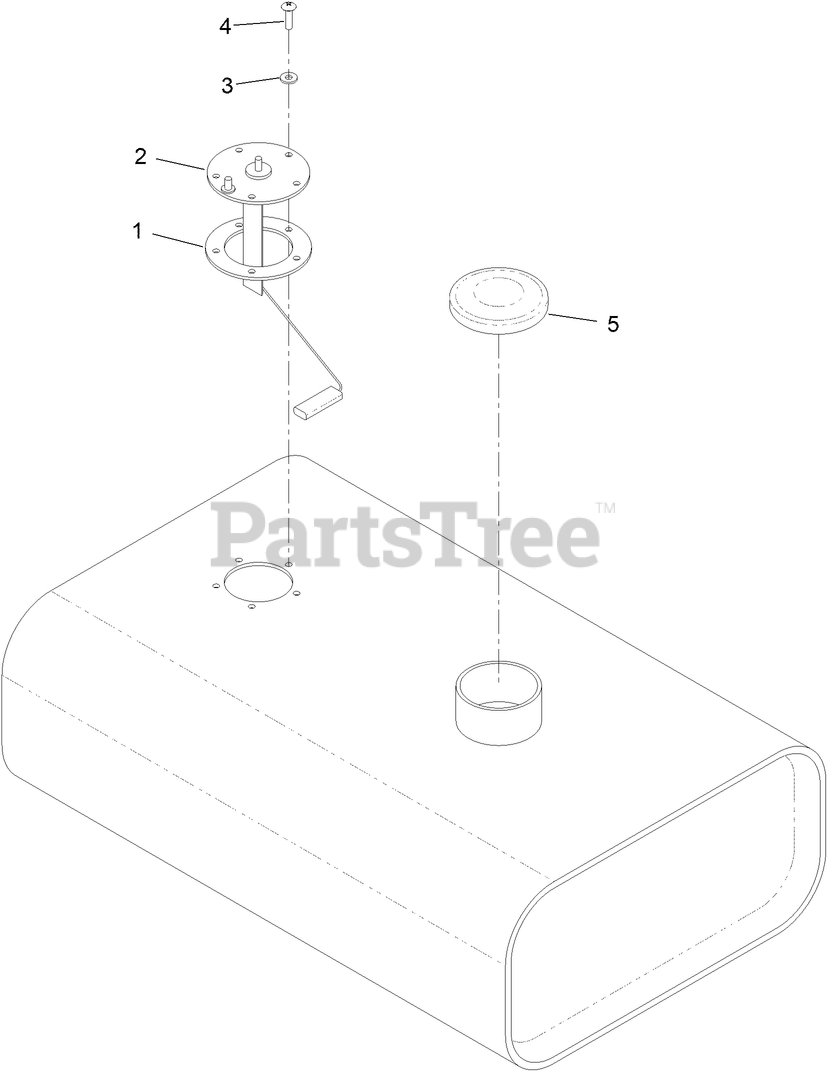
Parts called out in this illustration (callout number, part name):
1	GASKET-FUEL
2	FUEL SENDER
3	WASHER-SEAL
4	SCREW-HEAD, TRUSS
5	CAP-FUEL
